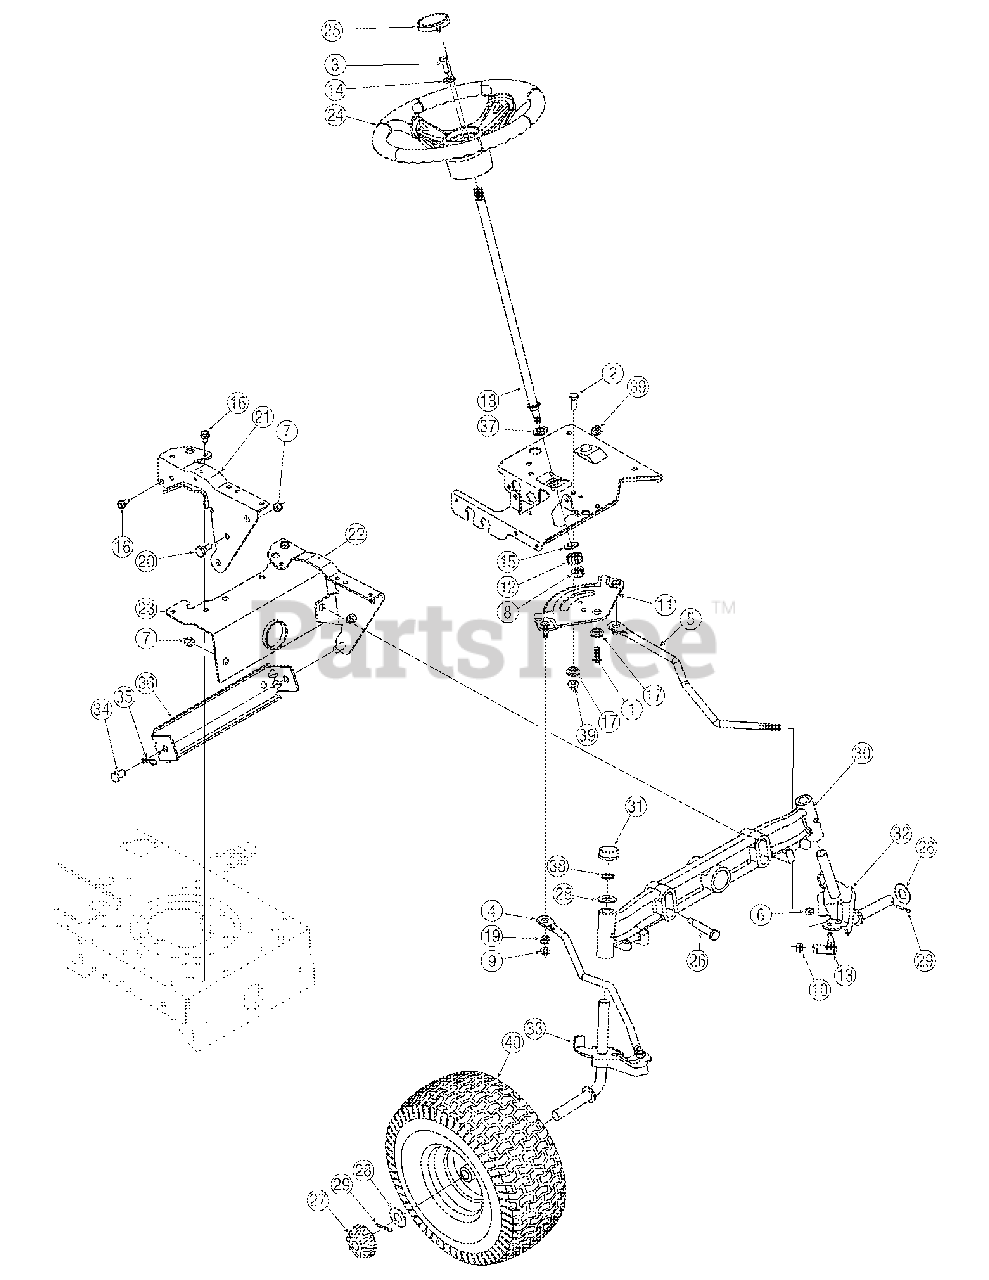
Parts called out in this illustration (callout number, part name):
1	Hex Screw, 3/8-16, 1.00, Gr5
2	Hex Screw, 3/8-16, 1.00, Gr5
3	Hex Screw, 5/16-18, 1.00,
4	Link, Drag, RH
5	Link, Drag, LH
6	Nut, Hex Lock, 3/8-24
7	Nut, Flange Lock, 3/8-16, Grf
8	Nut, Flange Lock, 7/16-20
9	Nut, Flange Lock, 5/16-18,
10	Nut, Jam, 7/16-20, Gr2
11	Gear, Steering, 11/90 Ratio
12	Gear, Pinion, Steering
13	Ball Joint, 7/16-20, Lock
14	Washer, Flat, .406 x .875 x
15	Washer, Flat, .51 x 1.12 x
16	Screw, 5/16-18, 0.750
17	Spacer, Shoulder, .38 x 1.00
18	Shaft, Steering, .625 OD x
19	Plastic Bushing .380 ID
20	Screw, Shoulder, .498 x .340
24	Steering Wheel
25	Steering Wheel Cap
26	Shoulder Screw, .5 x 2.380,
27	Deluxe Hub Cap
28	Flat Washer, .78 x 1.589 x
29	Cotter Pin, 5/32 x 1.25
30	Pivot Bar, Cast Iron
32	LH Axle Assembly, .750
33	RH Axle Assembly, .750
34	Pin, Clevis, .50 x .78
35	Cotter Pin, Internal, .080 x
37	Hex Flange Bearing
39	Flange Lock Nut, 3/8-16
40	Wheel Assembly Complete, 15
40	Tire Only 15 x 6 x 6
